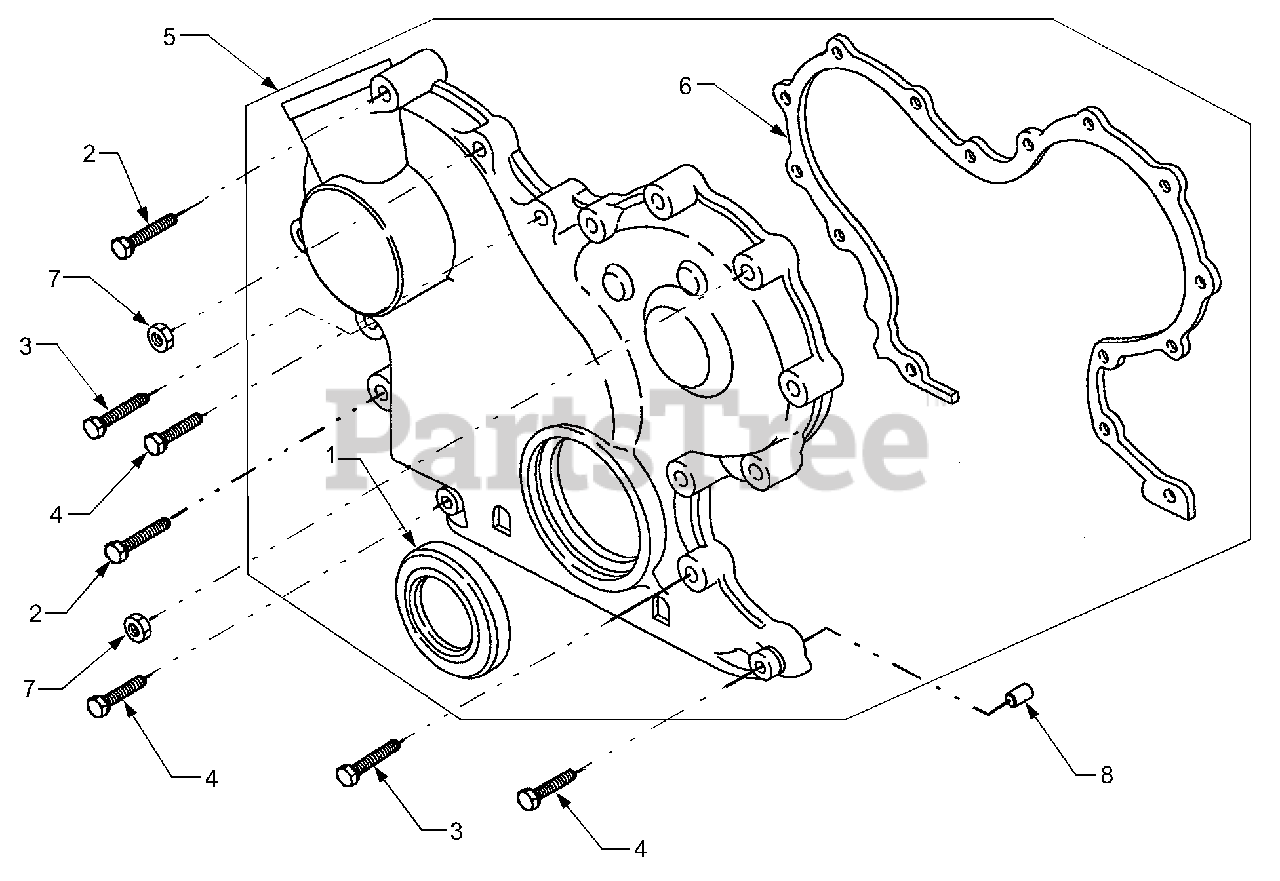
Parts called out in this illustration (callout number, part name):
1	Seal, Oil
2	Screw, Hex, 6mm
3	Screw, Hex, 6mm
4	Screw, Hex, 6mm
5	Cover Assembly, Gear
6	Gasket, Gear Cover
7	Nut, Hex Metric
8	Pin, Locating
